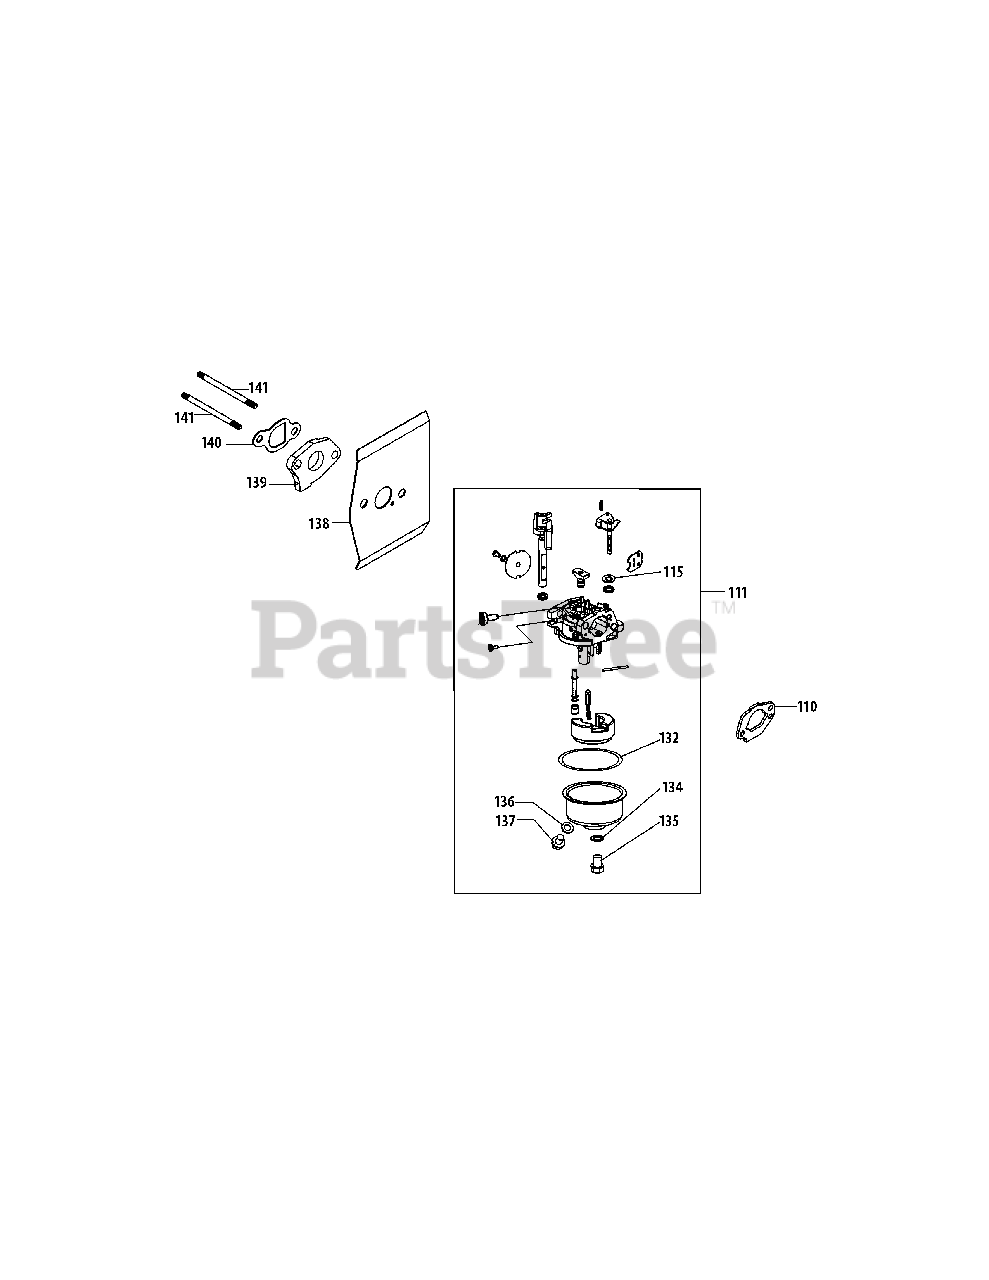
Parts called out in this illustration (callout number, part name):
110	Carburetor Gasket Plate
111	Carburetor Assembly
115	Choke Shaft Washer
132	Fuel Bowl O-Ring
134	Fuel Bowl Gasket
135	Fuel Bowl Mounting Bolt
136	Fuel Drain Plug Gasket
137	Fuel Drain Plug
138	Carburetor Gasket
139	Carburetor Insulator
140	Carburetor Insulator Gasket
141	Carb Stud M6X92
